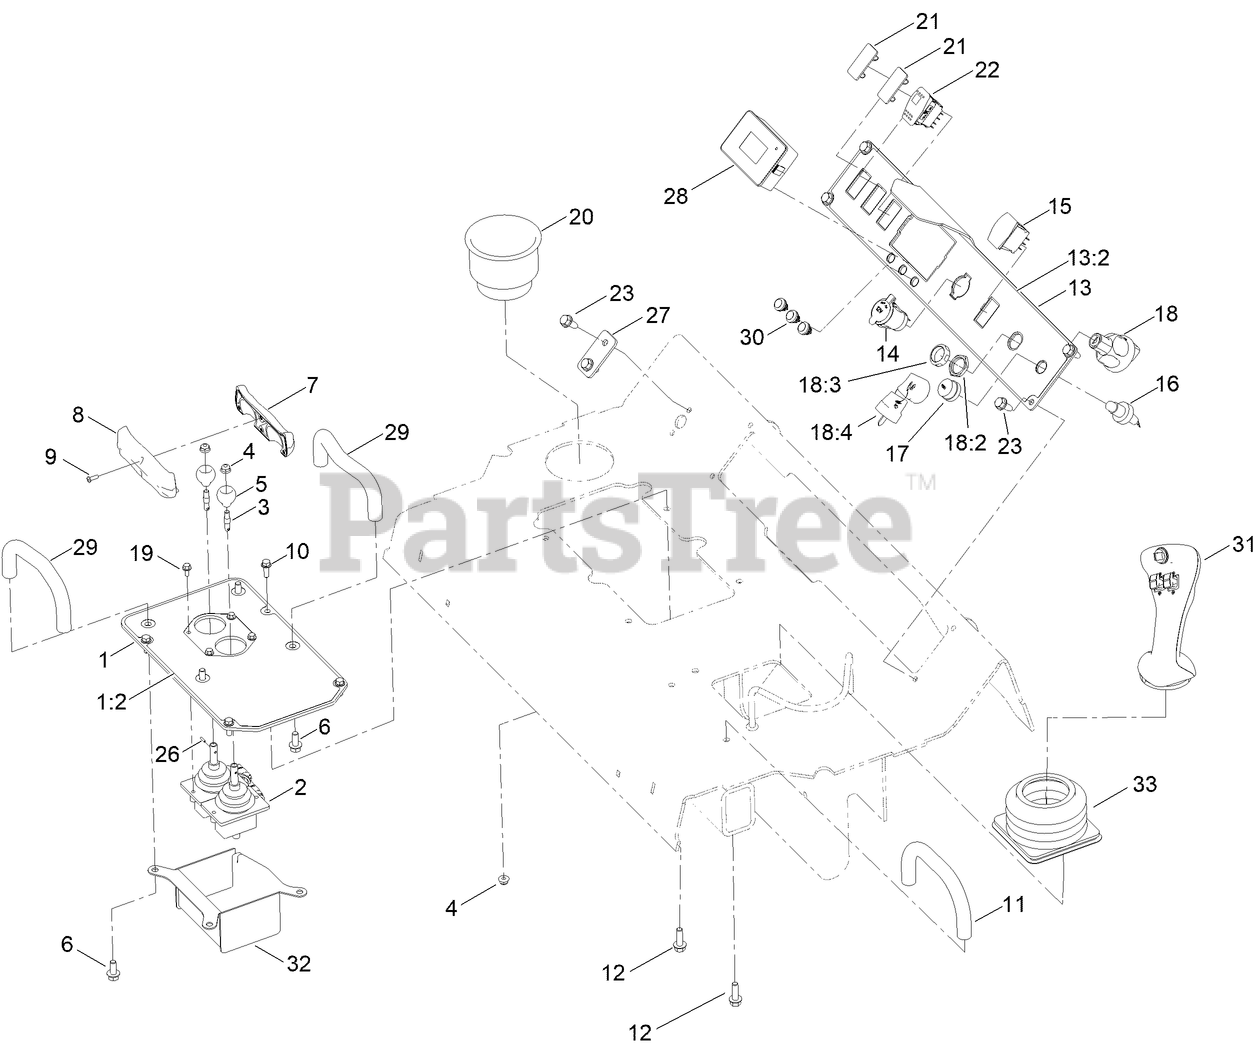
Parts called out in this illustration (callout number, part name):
1	PLATE-CONTROLS, TRACTION
1:2	DECAL-TRACTION
2	LEVER-CONTROL
3	SHAFT-HANDLE
4	NUT-HF
5	BALL-TRACTION
6	SCREW-HHF
7	HANDLE-FRONT
8	HANDLE-REAR
9	SCREW
10	SCREW-HHF
11	BAR-REFERENCE
12	SCREW-HHF
13	PLATE-CONTROL, MAIN
13:2	DECAL-CONTROLS
14	PORT-POWER, 12V
15	SWITCH
16	SWITCH-HORN
17	NUT-WEATHERPROOF
18	IGNITION SWITCH ASM
18:2	NUT-HEX
18:3	NUT-FACE
18:4	SET-KEY, IGNITION
19	SCREW-HFH
20	CUP-HOLDER
21	PLUG-HOLE
22	SWITCH
23	SCREW-HWH
26	PIN-ROLL
27	PLATE-BLANK
28	TDM 2002
29	BAR-REFERENCE
30	SWITCH-PUSHBUTTON
31	HANDLE-JOYSTICK,
32	COVER-VALVE
